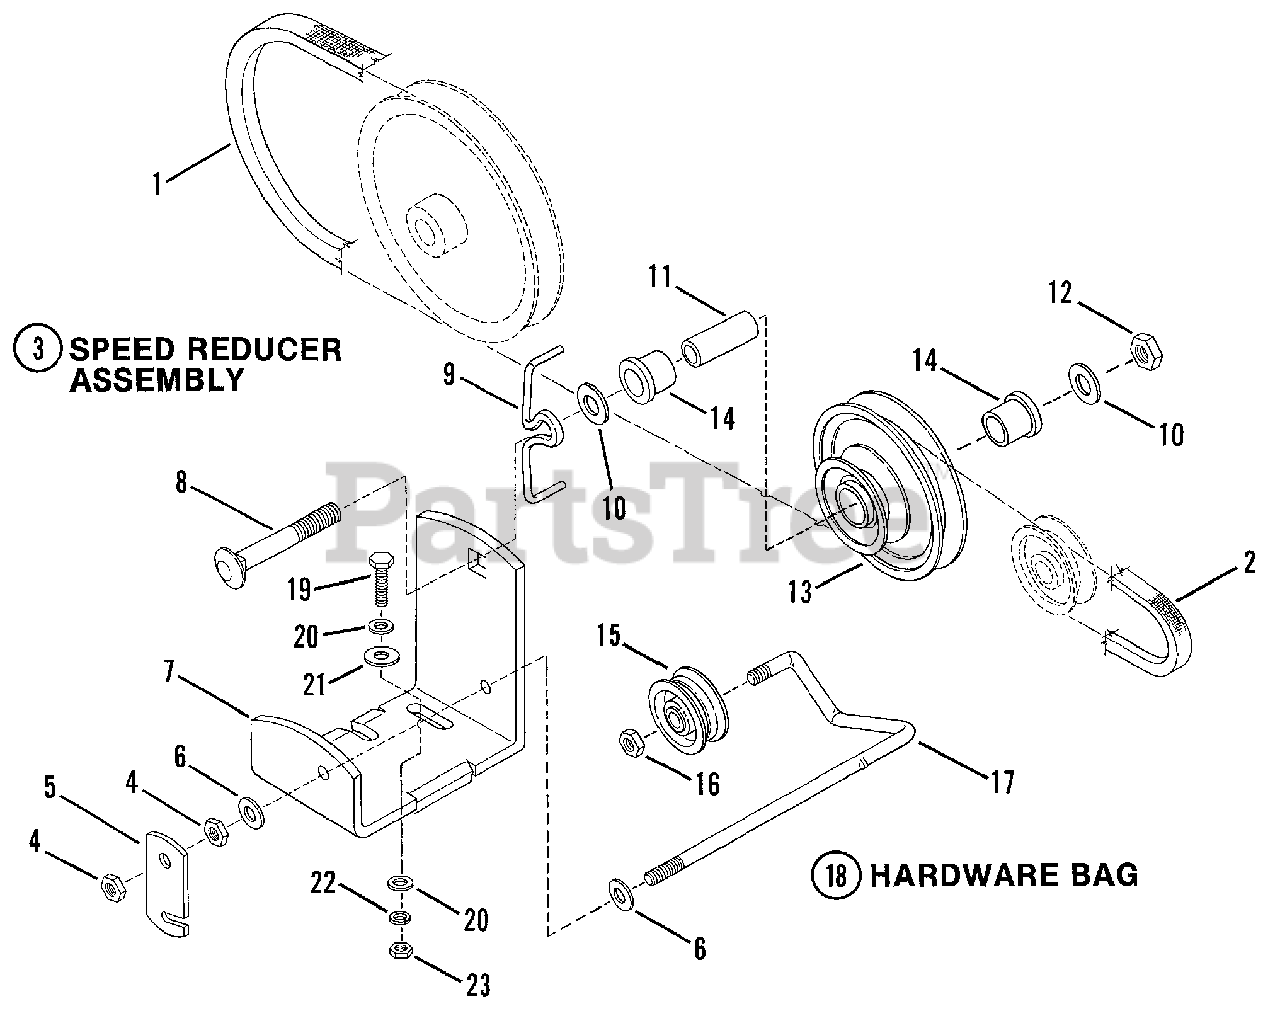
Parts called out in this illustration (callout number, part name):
1	V-BELT (Reducer to Chain Drive 37")
2	V-BELT (Engine to Reducer 26.75")
3	(NLA) SPEED REDUCER ASSM'Y.
4	NUT, 3/8-24 Hex
5	LINK, Idler
6	WASHER, 3/8" Flat
7	(NLA) MOUNT, Speed Reduction
8	BOLT, 1/2-13x2-3/4" Carriage
9	GUIDE, Belt
10	WASHER, 1/2 Flat
11	RACE, Bearing
12	NUT, 1/2-13 Hex
13	SHEAVE ASSM'Y.
14	BEARING
15	PULLEY, Idler
16	NUT, 3/8-24 Hex Lock
17	ARM, Pulley
18	(NLA) HARDWARE BAG
19	SCREW, 5/16-18x1" Hex Head Cap
20	WASHER, 5/16 Flat
21	WASHER, 7/16 Flat
22	WASHER, 5/16 Split Lock
23	NUT, 5/16-18 Hex
